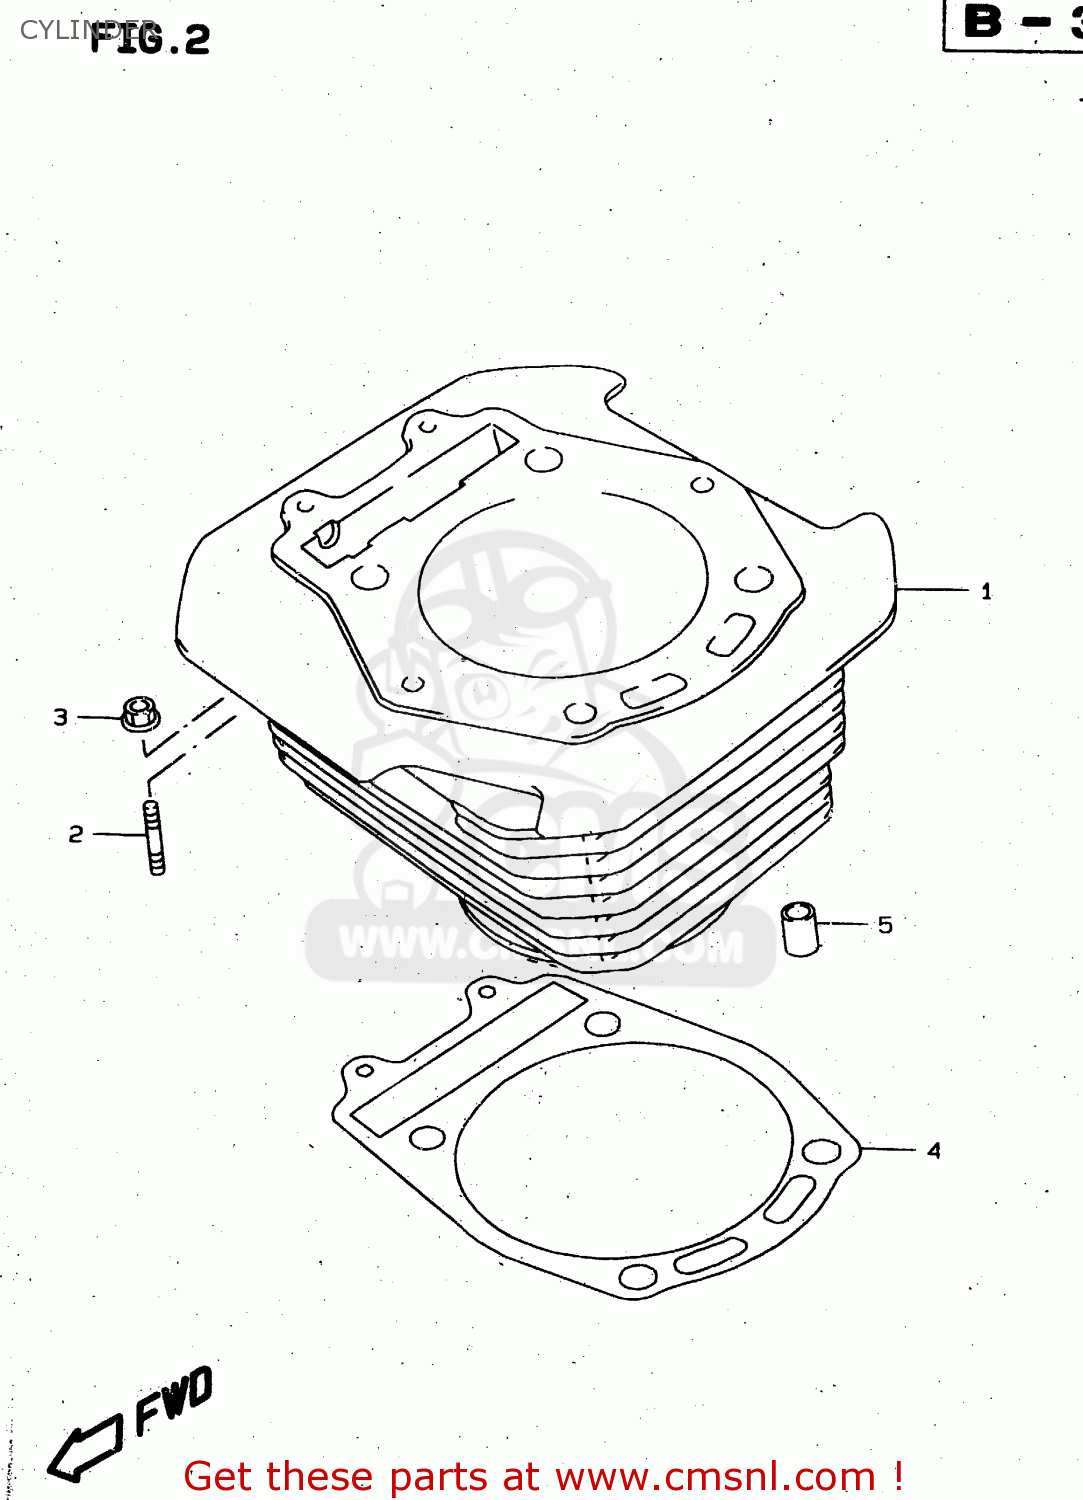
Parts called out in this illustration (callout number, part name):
1	CYLINDER
2	STUD 6X20
3	NUT
4	GASKET,CYLINDER (NAS)
5	PIN
